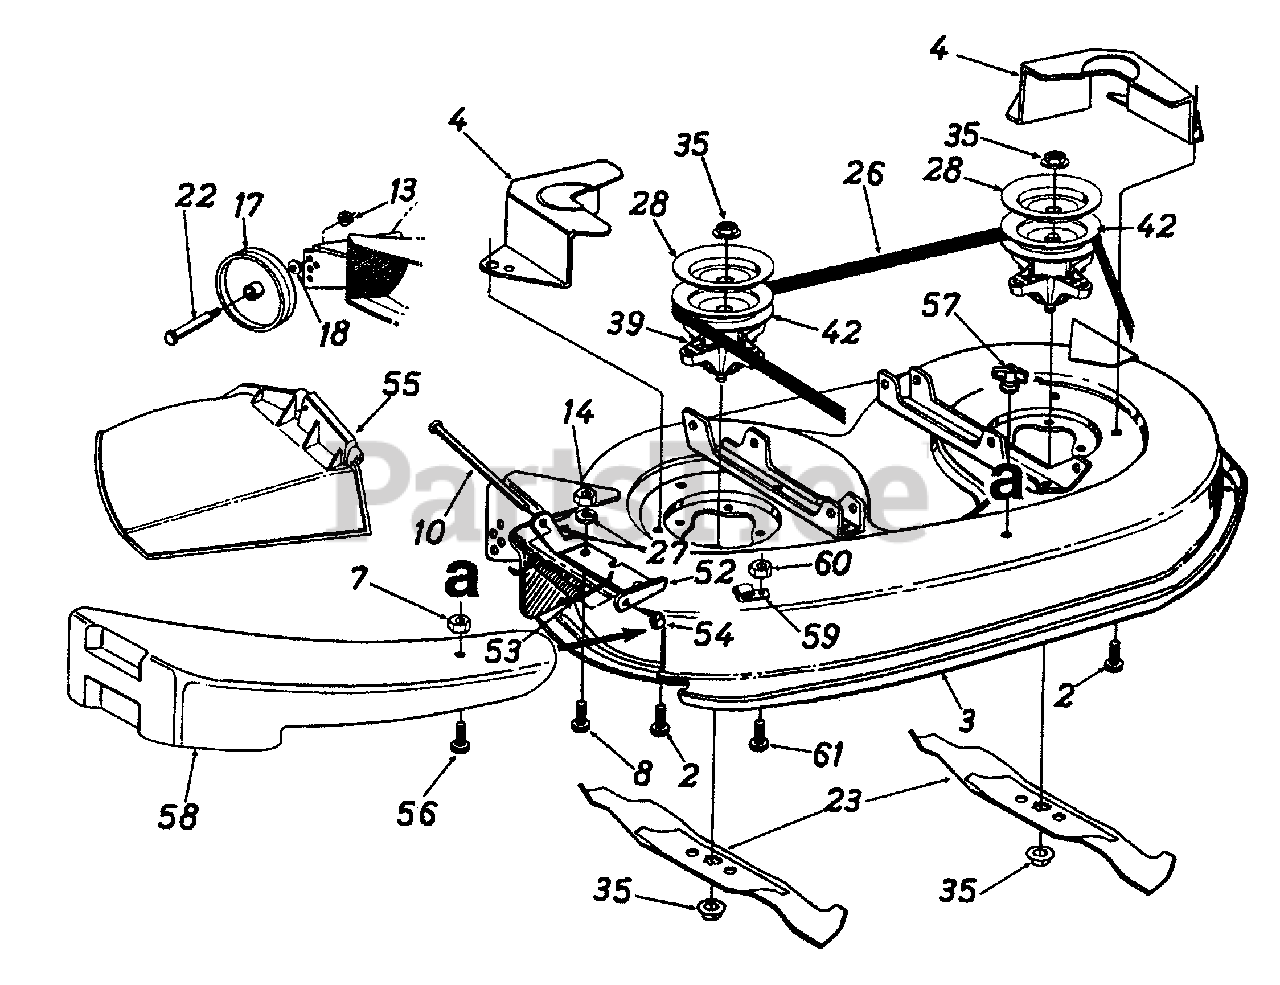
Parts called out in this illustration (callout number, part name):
2	Hex Wash. Hd. TT-Tap Scr. 5/16-18 x .75" Lg.
7	Hex L-Nut 1/4-20 Thd.
8	Hex Bolt 1/4-20 x .62"
10	Hinge Pin
13	Hex Top L-Nut 3/8-16 Thd.
14	Hex Nut 1/4-20 Thd. (Gr. 5)
17	Deck Wheel-5"
18	Bell-Wash..40" I.D. x .88" O.D.
22	Shld. Bolt .498" Dia. x 1.53"
23	3 in 1 Blade
26	V-Belt
27	Bell-Wash. 1/4" I.D.
28	Brake Disc
35	Hex Flange Nut 5/8-18 Thd.
39	Blade Spindle Ass'y. Comp.
42	5" Dia. Pulley
52	Hinge Mtg. Brkt.
53	Torsion Spring
54	Push Nut
55	Chute Ass'y. Comp.
56	Hex Bolt 1/4-20 x 1" Lg.
57	Wing Nut 1/4-20 Thd.
58	Mulching Plug
59	Retainer Hook Brkt.
60	Hex Sems Nut 1/4-20 Thd.
61	Hex Bolt 1/4-20 x .62" Lg.
